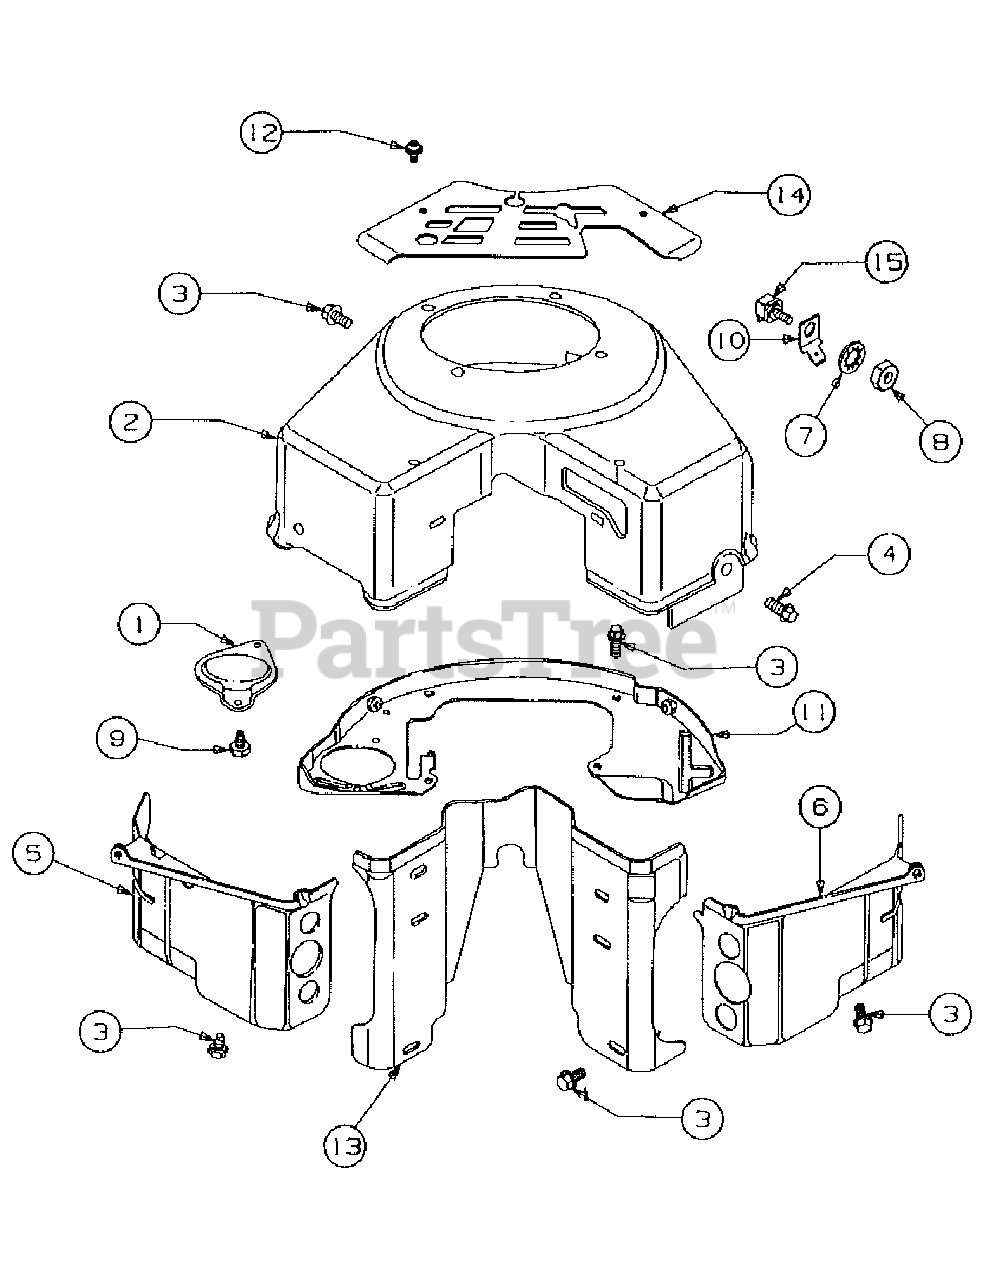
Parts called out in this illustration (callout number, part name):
1	Cover, Starter
2	Housing, Blower
3	Screw, Sem
4	Screw, Sem
5	Cover, Air Guide
6	Cover, Air Guide
7	Washer, Lock
9	Screw, Sem
10	Terminal, Spade
11	Back Plate Assembly
12	Screw, Sem
13	Valley Cover, Air Guide
14	Cover Carburetor
15	Insulator Assembly
